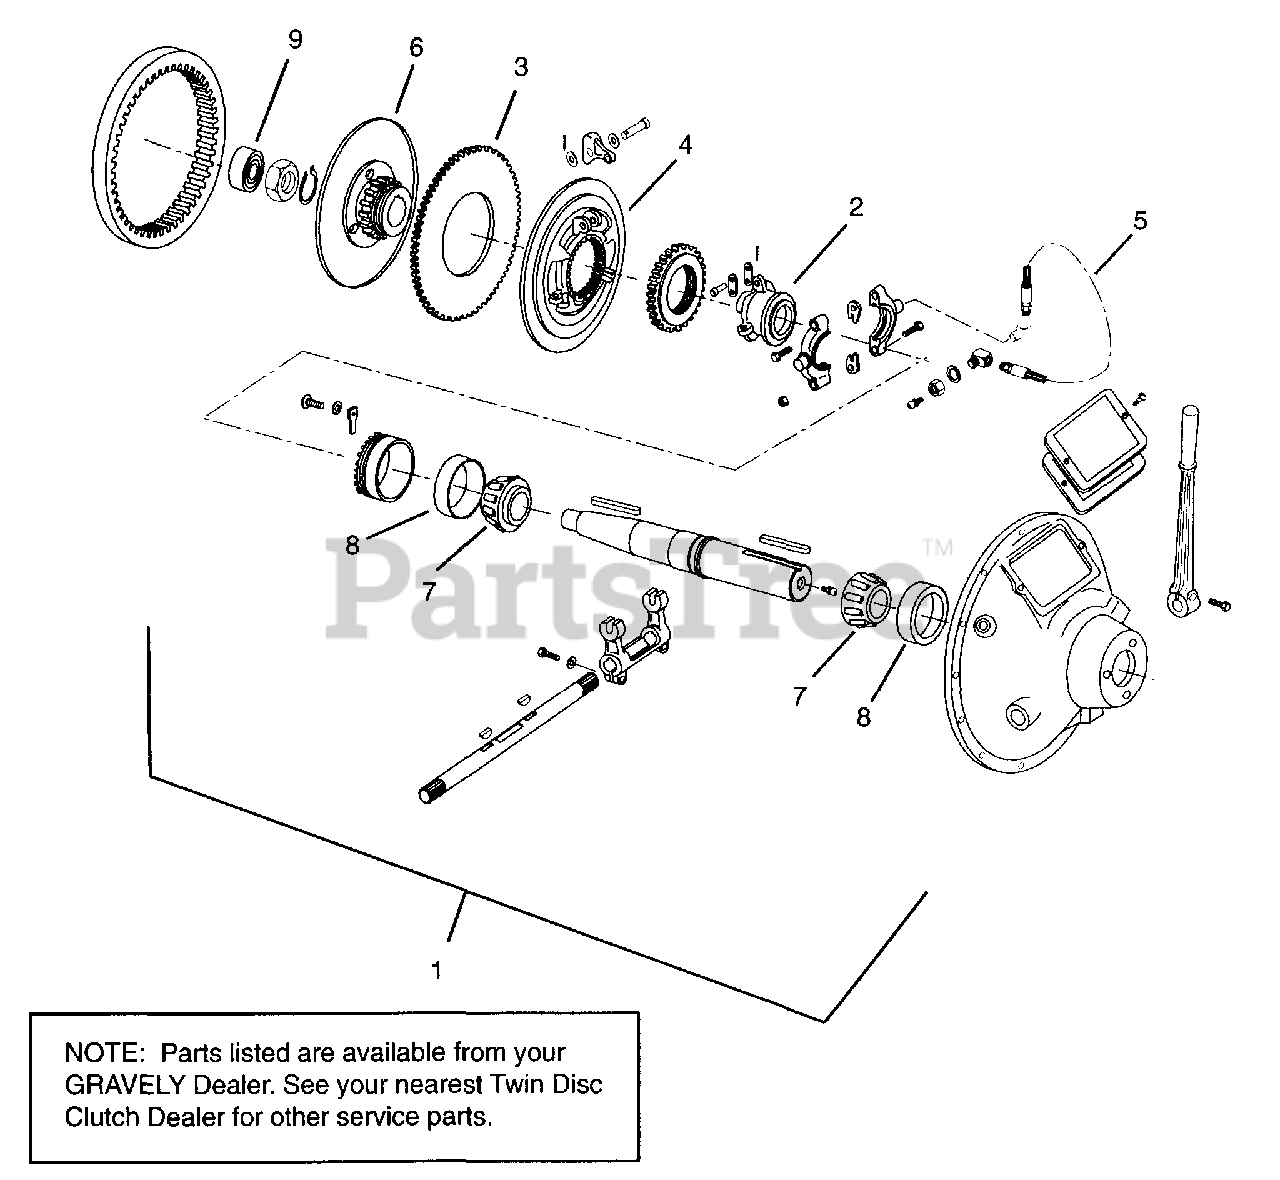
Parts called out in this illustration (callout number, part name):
1	Clutch Assembly
2	Sleeve-Sliding
3	Plate-Friction
4	Plate-Pressure
5	Hose-Grease
6	Plate-Hub & Backing
7	Bearing-Cone
8	Bearing-Cup
9	Bearing-Ball-Pilot
